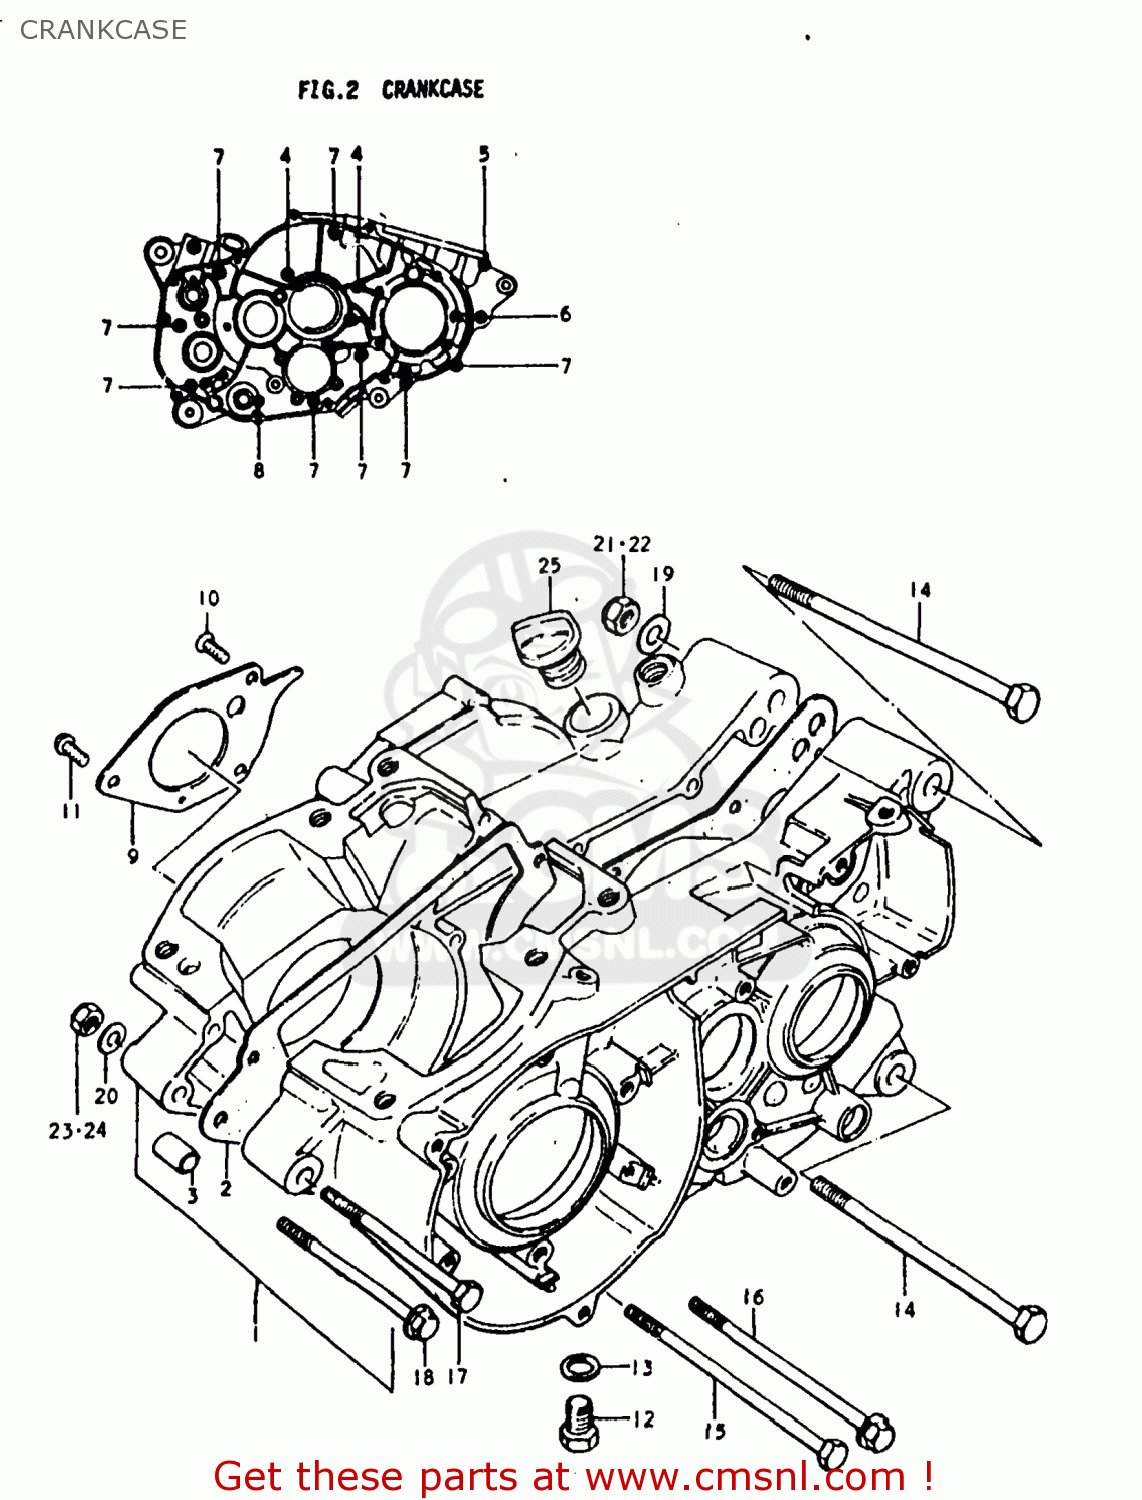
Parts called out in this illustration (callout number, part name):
1	CRANKCASE SET
2	GASKET,CRANKCASE (MCA)
3	PIN
4	SCREW
5	SCREW 6X65
6	SCREW
7	SCREW (6X45)
8	SCREW (6X35)
9	PLATE,OIL RESERVOIR
10	SCREW
11	SCREW
12	PLUG
13	GASKET(14X19.2X2) (NAS)
14	BOLT
15	BOLT 8X120
16	BOLT
17	HEXAGON BOLT 8X80
18	BOLT
19	WASHER
20	WASHER
21	NUT
22	NUT
23	NUT
24	NUT
25	PLUG
